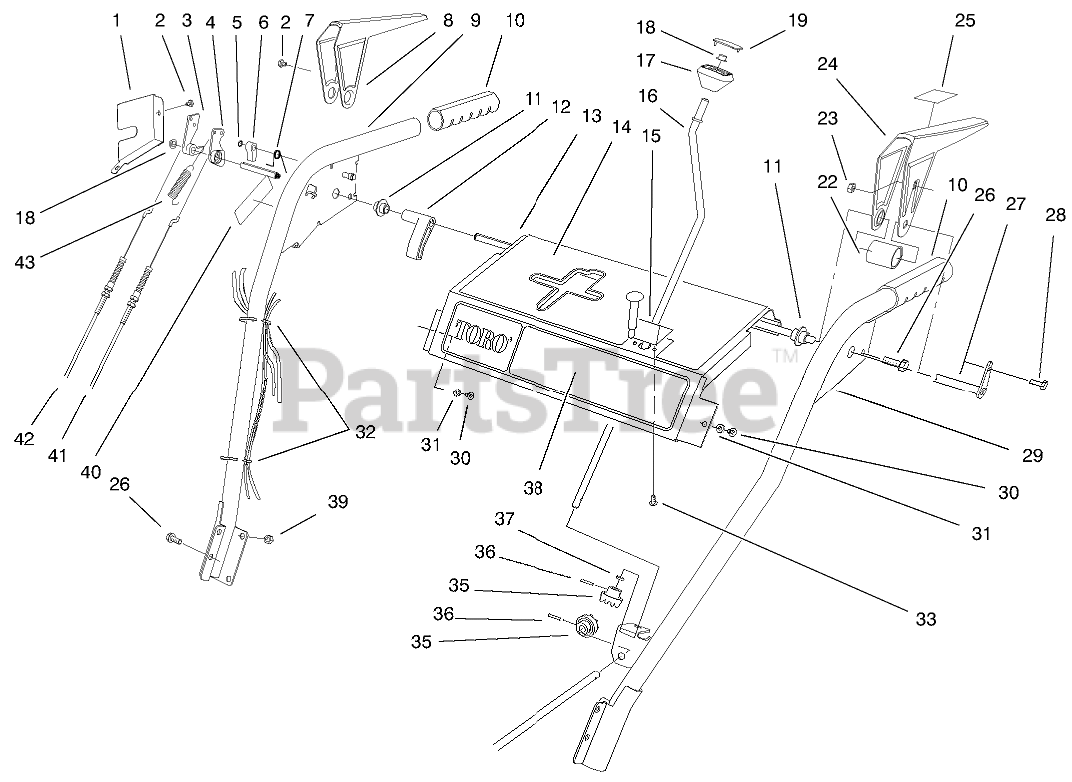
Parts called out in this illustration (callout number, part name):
1	COVER-LOCK, LEVER
2	SCREW-HH
3	TANG-LOCKING
4	CAM-RELEASE
5	E-RING-RETAINER
6	LATCH-LOCKING
7	SPRING-TORSION
8	LEVER-TRACTION, RH
9	RH Handle ASM, 24"-32"
10	GRIP-HANDLE
11	BUSHING-LEVER
12	LEVER-TRIP
13	CONTROL PANEL/DECAL ASM (38542)
13	CONTROL PANEL/DECAL ASM (38543)
14	Decal-Top, Panel (Only On: 38542)
14	Decal-Control (Only On: 38546)
15	PLATE-GUIDE
16	CRANK-ROD, CHUTE
17	KNOB-CONTROL, CHUTE
18	RETAINER-PUSH ON
19	COVER-KNOB
22	SPACER-LEVER, TRACTION
23	NUT-LOCK, NI
24	LEVER-TRACTION, LH
25	Decal-Lever (Only On: 38542)
26	SCREW-HWHTF
27	CROSS ROD ASM
28	SCREW-HWH
29	LH HANDLE ASM
30	SCREW-HWHTF
31	WASHER-FLAT
32	TIE-CABLE
33	SCREW
35	GEAR-UNIVERSAL
36	PIN-SPRING
37	WASHER-RUBBER
38	DECAL-FRONT PANEL (824)
39	NUT-LOCK, NI
40	Decal-Adjustment (Only On: 38546)
40	Decal-Warning (Only On: 38542)
41	CABLE-TRACTION
42	CABLE-IMPELLER
43	SPRING-EXTENSION
